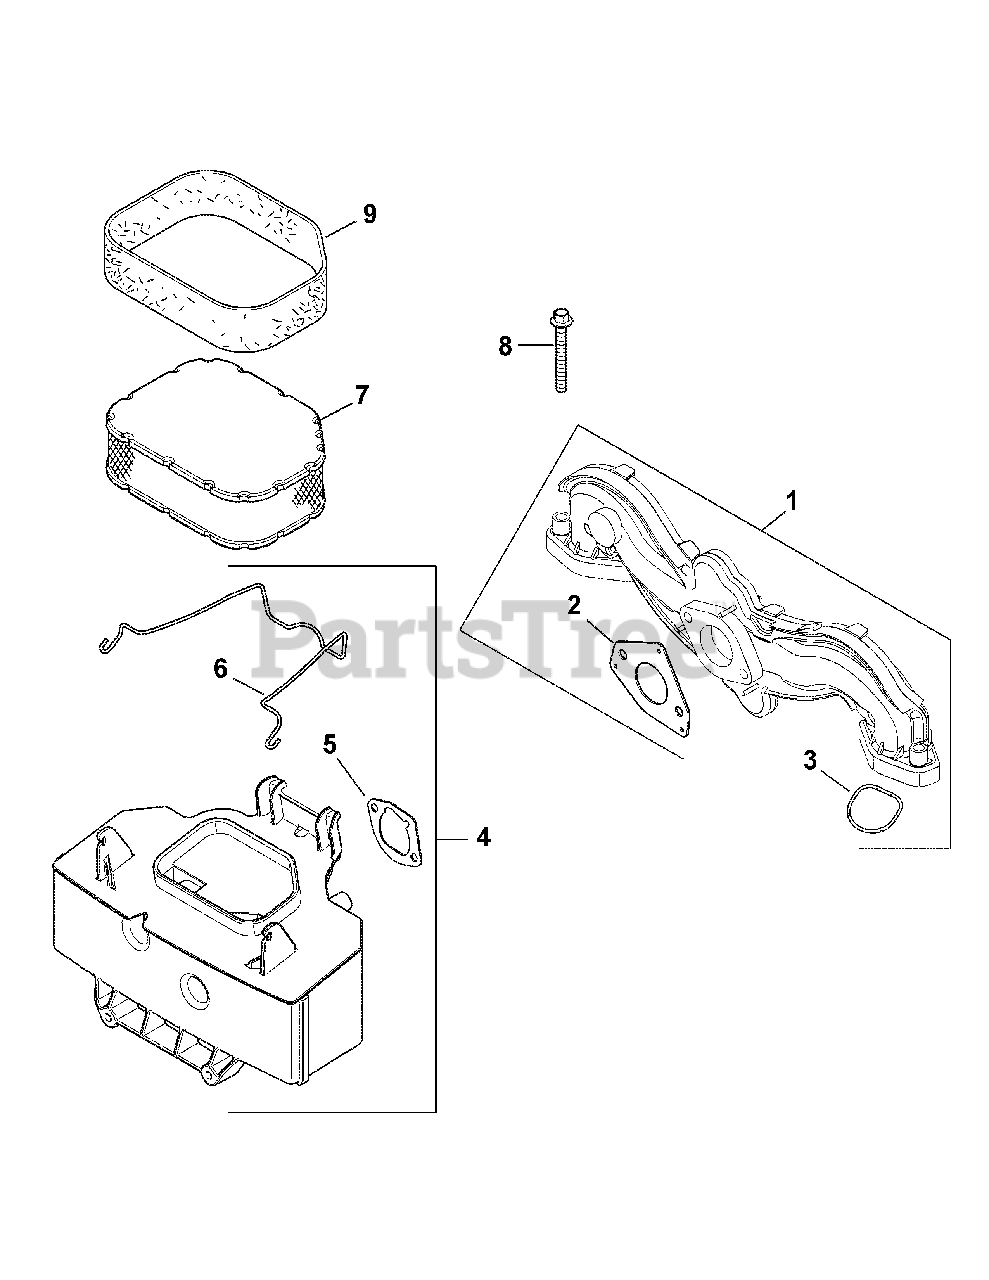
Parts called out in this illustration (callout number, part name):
1	Manifold, Intake
2	Gasket, Carburetor
3	O-Ring, Intake Port
4	Base, Air Cleaner w/Gasket, Latch
5	Gasket, Air Cleaner Base
6	Latch, Air Cleaner Element
7	Element, Air Filter
8	Screw, Flange, M6 x 1.0 x 40
9	Pre-Cleaner, Element
